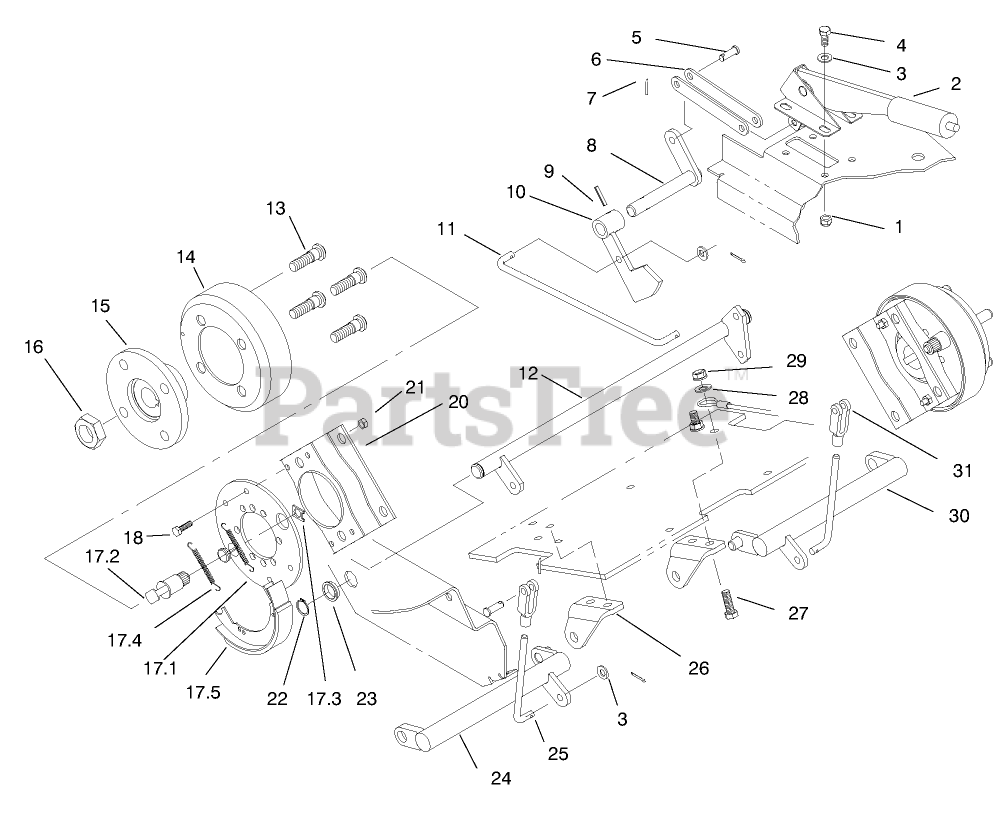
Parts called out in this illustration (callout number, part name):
1	NUT-LOCK, NI
2	LEVER-BRAKE
3	WASHER-PLAIN
4	SCREW-HH
5	PIN-CLEVIS
6	LINK - BRAKE
7	PIN-COTTER
8	WA - TRANSFER SHAFT
9	PIN-SPIRAL
10	WA - BRAKE HUB
11	ROD - BRAKE
12	WA - TORSION SHAFT
13	STUD-DRIVE
14	DRUM-BRAKE
15	Hub-Wheel
16	NUT-LOCK
17	BrakeASM
17.1	PLATE-BACKING
17.2	Cam Shaft
17.4	SPRING-RETURN
17.5	SHOE-BRAKE
18	SCREW-HH
20	Bracket-Brake
21	NUT-LOCK, NI
22	Ring-Snap
23	BUSHING
24	WA - BRAKE LEVER RH
25	ROD - LINK,BRAKE
26	MOUNT-LEVER, BRAKE, RH
27	SCREW-HH
28	WASHER-FLAT
29	NUT-LOCK, NI
30	LH BRAKE LEVER WA B
31	YOKE
